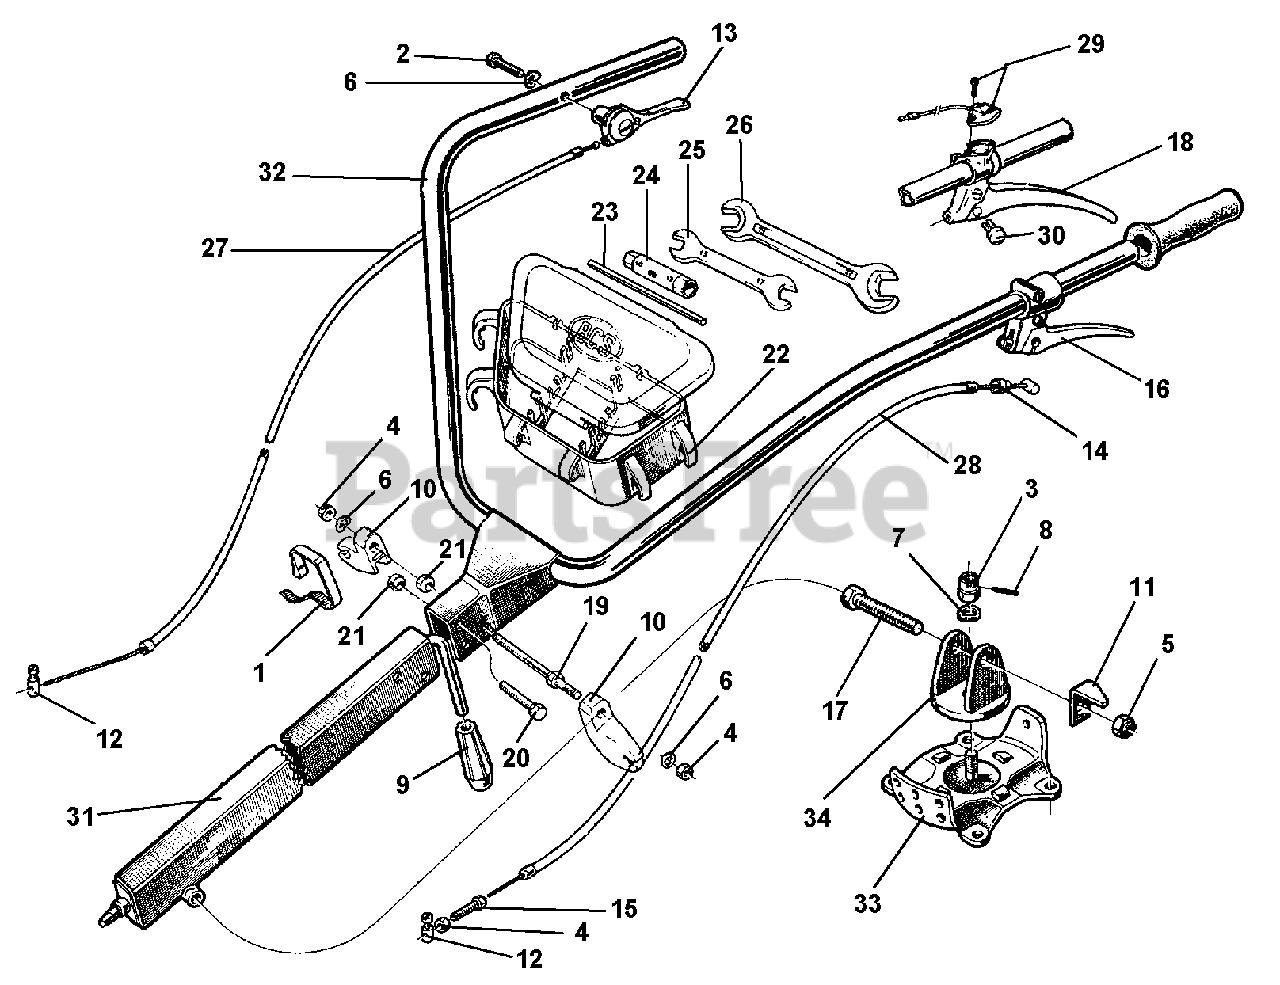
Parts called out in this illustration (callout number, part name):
2	SCREW M8 X 35
3	NUT, HEX INT. M12 UNI 5593 6S
5	NUT, SELF LOCKING M12
6	WASHER, LOCK 8.4
7	WASHER, LOCK 13
8	PIN, LOCKING SW 3 X 22 SPIRAL
10	SUPPORT CONTROL ROD CUT
11	LOCKING PLATE
12	CLAMP, CABLE
13	LEVER, ACCELERATOR
14	END, SHEATH
15	SCREW, ADJUSTING M8
16	CLUTCH LEVER (DIESEL)
17	SCREW SPECIAL M12 X 70
18	CLUTCH LEVER
19	SCREW, SPECIAL
21	BEVEL NUT M8
23	PARALLEL PIN D 7 X 130
24	TUBE KEY 10 - 13
25	OPEN KEY 13 - 17
26	OPEN KEY 19 - 22
27	WIRE, SHEATH 1850 GAS
28	WIRE, SHEATH L-1280 CLUTCH/BR.
31	STEERING COLUMN
33	CAP WITH HOLE D.13
